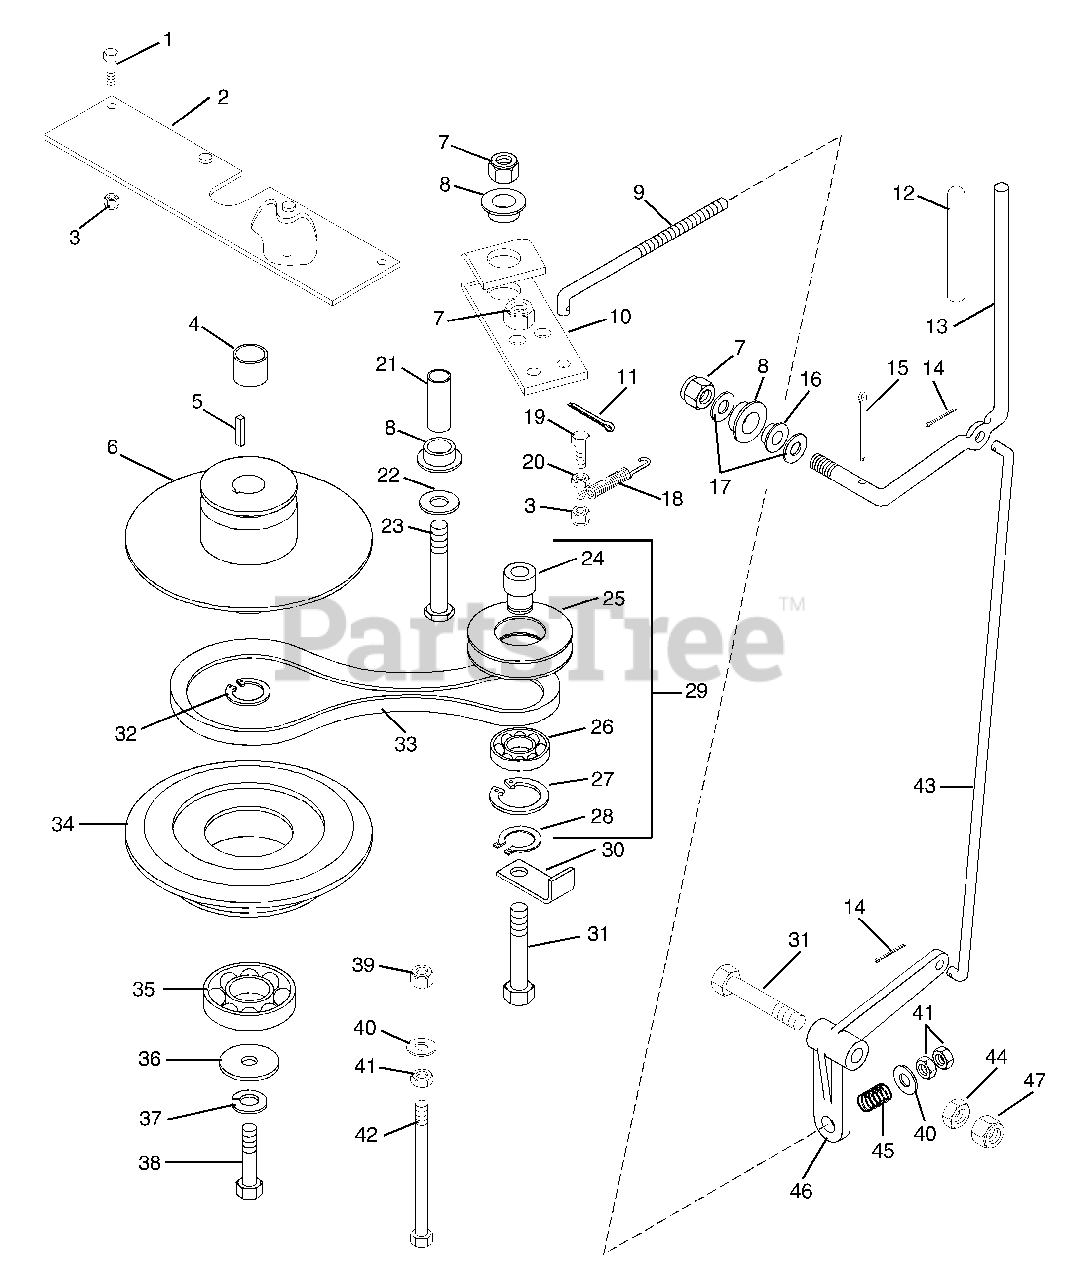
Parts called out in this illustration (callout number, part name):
1	Bolt-Hex .31-18 x .75 Grade 5
2	Weldment, Belt Guide
3	Nut-Locking-Nylon .312-18
4	Spacer, Manual Start
5	Key-Square .248 x 1.25 x .248
6	Hub, PTO & Drive Clutch
7	Nut-Locking-Nylon .50-13 Grade 5
8	Bushing-Flange .762 x 1.0 x .580 x 1.48
9	Rod, PTO Clutch Actuating
10	Arm, Idler Pivot
11	Pin-Cotter .12 x .75
12	Grip, PTO Lever
13	Lever, PTO Actuating
14	Pin-Cotter .09 x .75
15	Pin-Cotter .188 x 1.25
16	Bushing-Flange .515 x .750 x .745 x 1.00
17	Washer-Flat-Steel .531 x .750 x .100
18	Spring-Tension .061 x .50 x 3.5
19	Bolt-Hex .31-18 x 1.00 Grade 5
20	Nut-Hex .312-18
21	Bushing, Steel .560 x .745 x 2.04
22	Washer-Flat-Steel .531 x 1.062 x .095
23	Bolt,Hex 1/2-13 x 2.75
24	Bushing, Flange .515 x .787 x 1.41
25	Sheave, Idler
26	Bearing-Ball 1.85 x .787 x .55
27	Ring-Retaining-Internal 2.054 x .062
28	Ring-Retaining-Truarc
29	Assembly, Idler Sheave
30	Guard, Belt
31	Bolt-Hex .50-13 x 2.50 Grade 5
32	Ring-Retaining
33	V-Belt A-Section
34	Sheave, Mower Clutch
35	Bearing-Ball 1.57 x 3.15 x .71
36	Washer-Special .469 x 2.000 x .250
37	Washer-Lock .44 Reg.
38	Bolt-Hex 10MM x 1.5 x 60MM
38	Bolt-Hex .44-20 x 2.50
39	Nut-Locking-Nylon .375-16
40	Washer-Flat-Steel .406 x .812 x .065
41	Nut-Hex .375-16
42	Bolt-Hex .38-16 x 4.00
43	Rod, PTO Control
44	Nut-Jam .50-13
45	Spring-Compression .125 x .78 x 1.00
46	Lever, PTO Clutch
47	Nut-Locking .50-13
